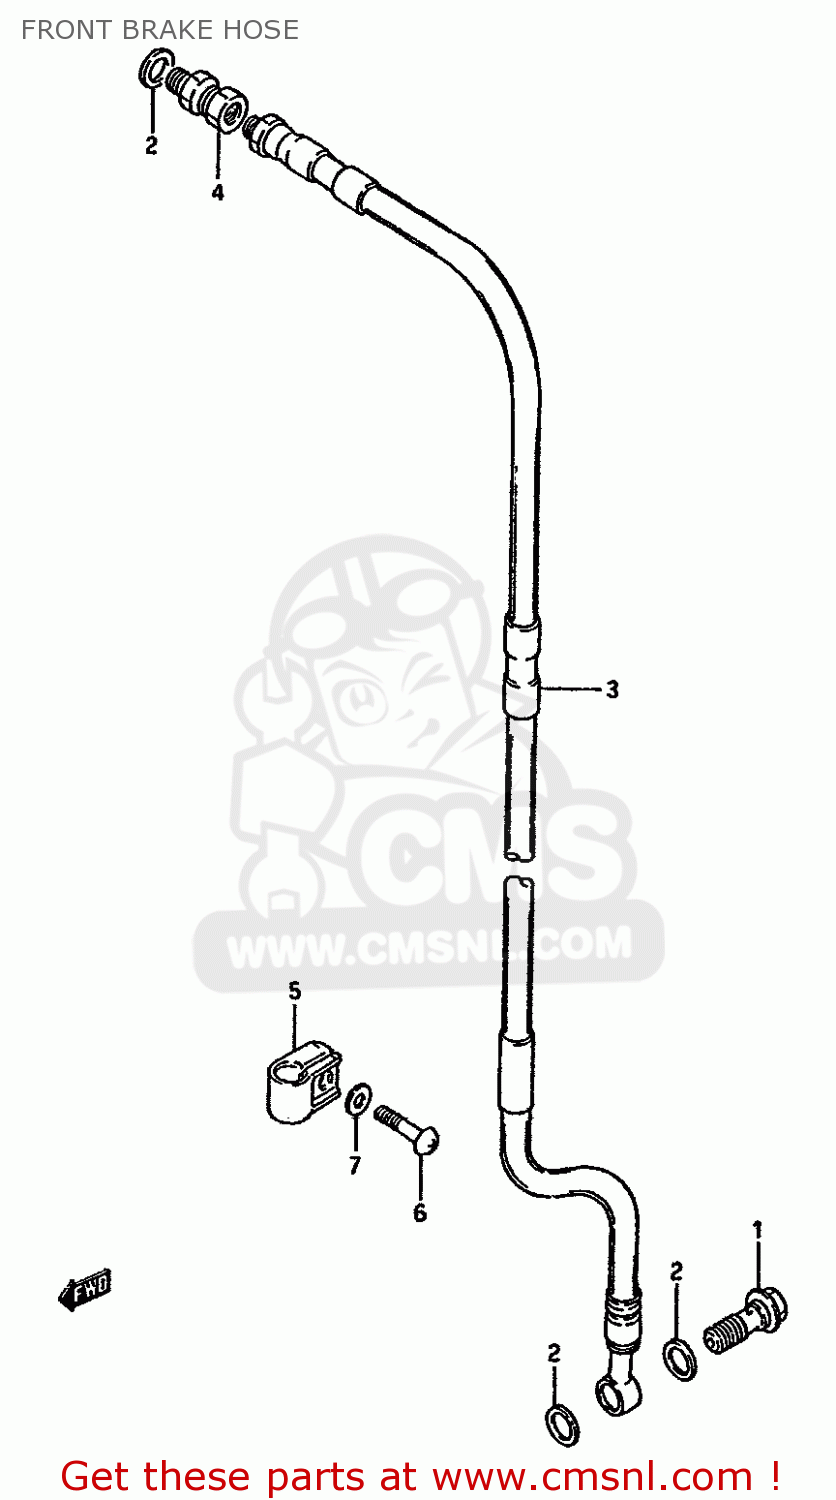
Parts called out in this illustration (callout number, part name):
1	BOLT UNION
2	WASHER(10X15X1.5)
3	HOSE,FRONT BRAKE
4	ADAPTER,BRAKE HOSE
5	CLAMP,FRONT BRAKE HOSE
6	SCREW
7	WASHER
